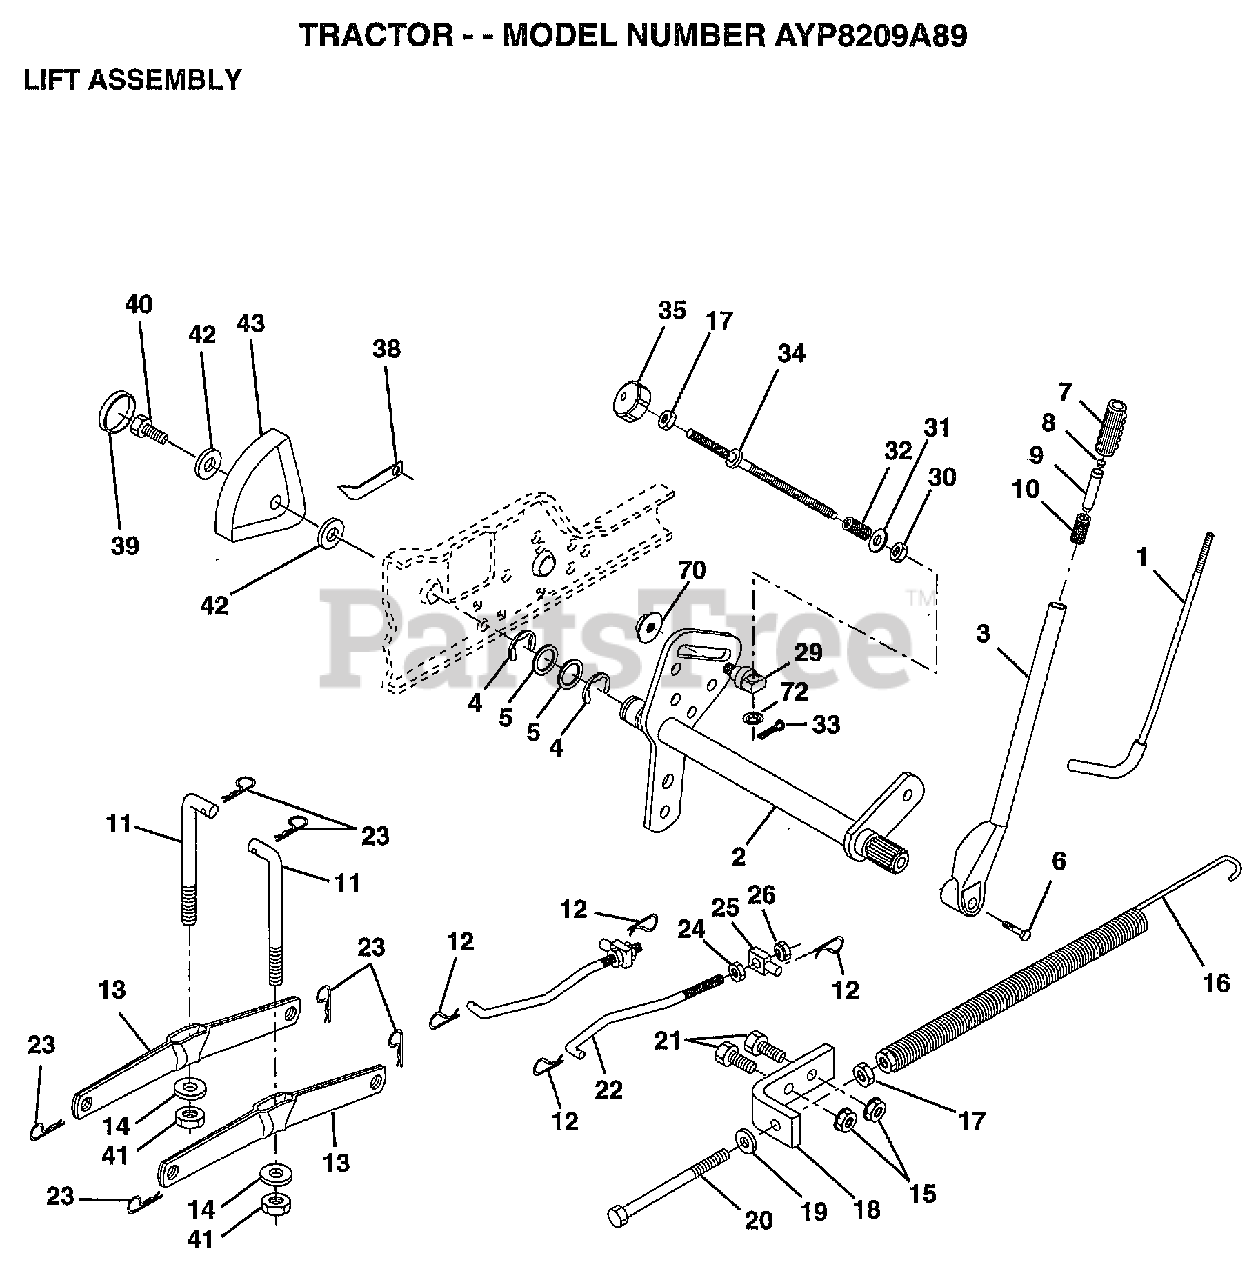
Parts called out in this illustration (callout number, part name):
1	LEVER ROD LT
2	SHAFT AMS LIFT
4	E-RING
5	WASHER
6	"BOLT,HEX"
7	GRIP HANDLE
10	SPRING T
11	LINK.LIFT.MWR.VGT
12	RETAINER SPRING
13	ARM SUSP REAR
14	BEARING PVT LH
17	NUT
18	BRACKET SPRING AS
19	WASHER
20	BOLT-ADJ SPRING T
21	BOLT
22	LINK.FRONT
24	NUT
25	TRUNION
26	NUT.LK.W/WSH.1/2.
29	TRUNNION
30	NUT T
31	WASHER
32	SPRING.COMP.INF.H
34	ROD.ADJ.LIFT
35	KNOB INF 3/8-16
38	POINTER-INDICAT
39	"PLUG,HOLE"
40	SCREW
41	NUT.CROWNLOCK.3/8
42	WASHER
43	HEIGHT INDICATOR
70	NUT.HXFLG.LOCK.
